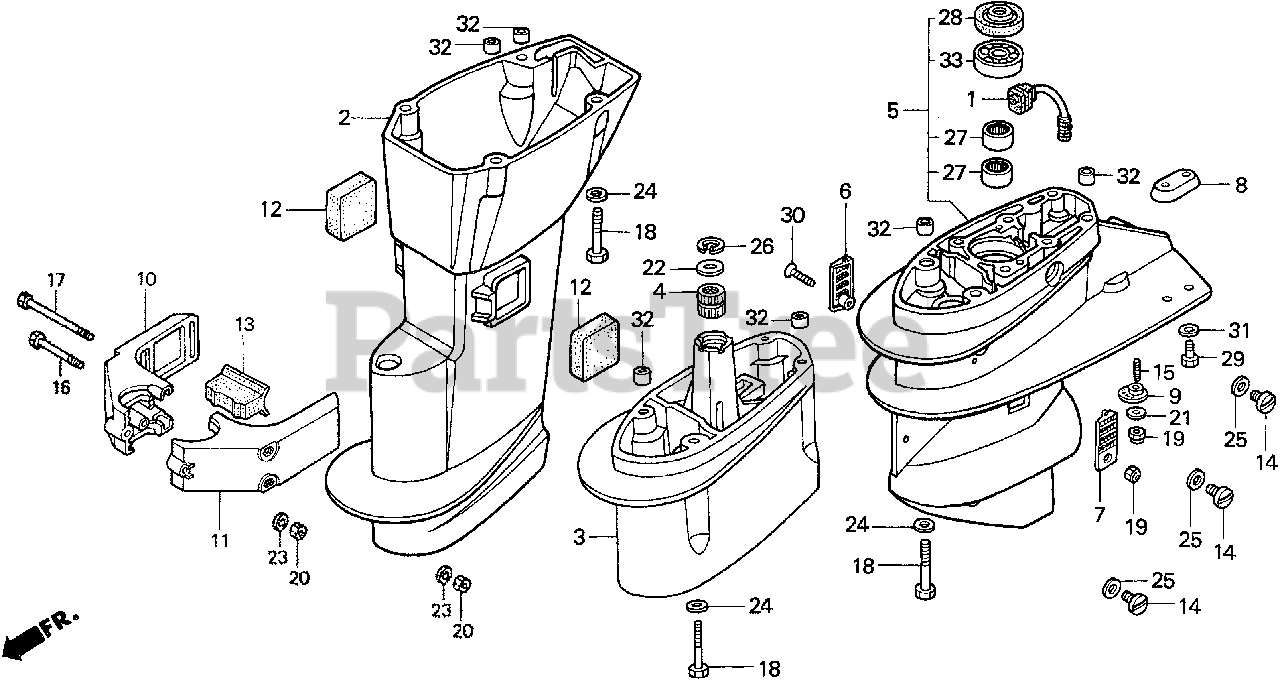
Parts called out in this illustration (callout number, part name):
1	TUBE, WATER (LOWER)
2	CASE, EXTENSION *NH210MC* (S) (AQUA SILVER METALLIC-C)
5	CASE, GEAR *NH210MC* (AQUA SILVER METALLIC-C)
6	SCREEN, R. WATER
7	SCREEN, L. WATER
8	METAL, ANODE
9	SCREEN, WATER (LOWER)
10	HOUSING, R. MOUNTING (LOWER) *NH210MC* (AQUA SILVER METALLIC-C)
10	HOUSING, R. MOUNTING (LOWER) *NH210MC* (AQUA SILVER METALLIC-C) (NOT AVAILABLE)
11	HOUSING, L. MOUNTING (LOWER) *NH210MC* (AQUA SILVER METALLIC-C)
11	HOUSING, L. MOUNTING (LOWER) *NH210MC* (AQUA SILVER METALLIC-C) (NOT AVAILABLE)
12	RUBBER, MOUNTING (LOWER) (A)
13	RUBBER, MOUNTING (LOWER) (B)
14	BOLT, OIL CHECK
15	BOLT, STUD (5X16)
16	BOLT, HEX. (6X45)
17	BOLT, HEX. (6X130)
18	BOLT, HEX. (8X50)
19	NUT, SELF-LOCK (5MM)
20	NUT, HEX. (6MM)
21	WASHER, PLAIN (5MM)
23	WASHER, PLAIN (6X13X1.5)
24	WASHER, PLAIN (8MM)
25	WASHER, NYLON (8MM)
27	BEARING, NEEDLE (15X21X12)
28	SEAL, WATER (15MM) (NOK)
29	BOLT, HEX. (6X18)
29	BOLT, HEX. (6X16)
30	SCREW, OVAL (5X25)
31	WASHER, PLAIN (6MM)
32	PIN A, DOWEL (10X14)
33	BEARING, RADIAL BALL (6302)
